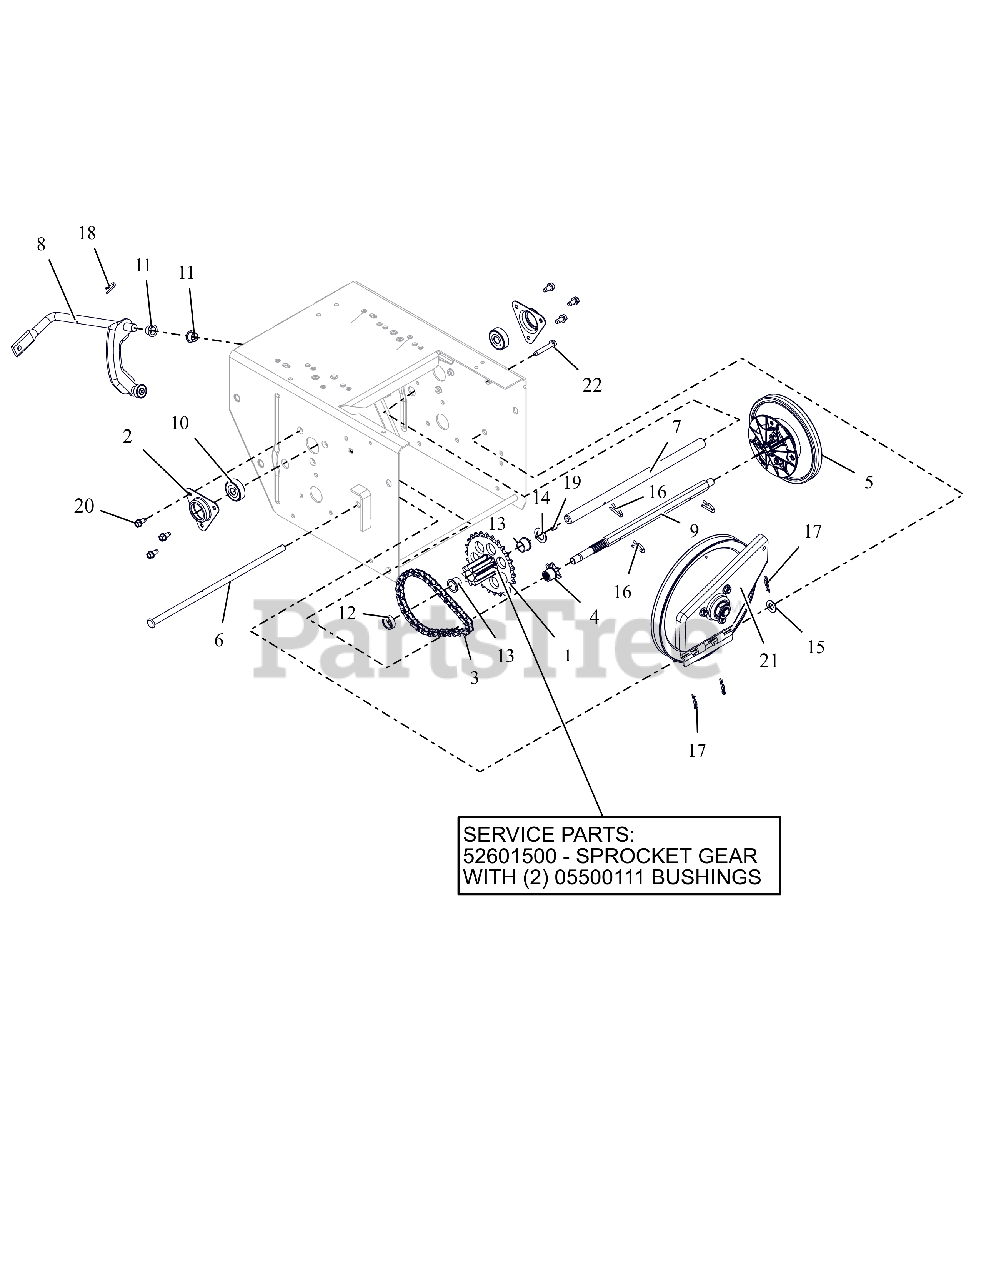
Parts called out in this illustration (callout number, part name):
1	PINION & SPROCKET
1	PINION & SPROCKET W/BUSHINGS
2	FLANGE, BEARING
3	CHAIN - #41, 32 PITCHES
4	SPROCKET, PINION 7T W/SPLINE
5	DISC, FRICTION DRIVE-ASSEMBLY
6	PIN, PIVOT
7	SHAFT, PINION
8	ARM, SHIFT - ASSEMBLY
9	SHAFT, HEX - HEAT TREATED
10	BRG-BALL .437X1.375X.437
11	BUSHING, POLYLINER-.50 SPLIT
12	BSHG-SLV, .635X.880X.305
13	BSHG-FLG .625X.750X.500X.875
14	WSHR-FL-STL .630X1.005X.062 YZ
15	@WSHR-FL-STL.406X.812X.065 YWZ
16	PIN, SPRING CLIP
17	PIN-HAIR, ENDRIES #25 YWZC
18	CLIP, SPRING
19	ZERK,FITTING .25X.125 DRIVE IN
20	SCR-TAP .25-20X.50 HWH TR YWZ
21	PLATE, SWING ASSEMBLY-DEEP
22	@SCR-TAP .25-20X1.50 HWH TR YZ
